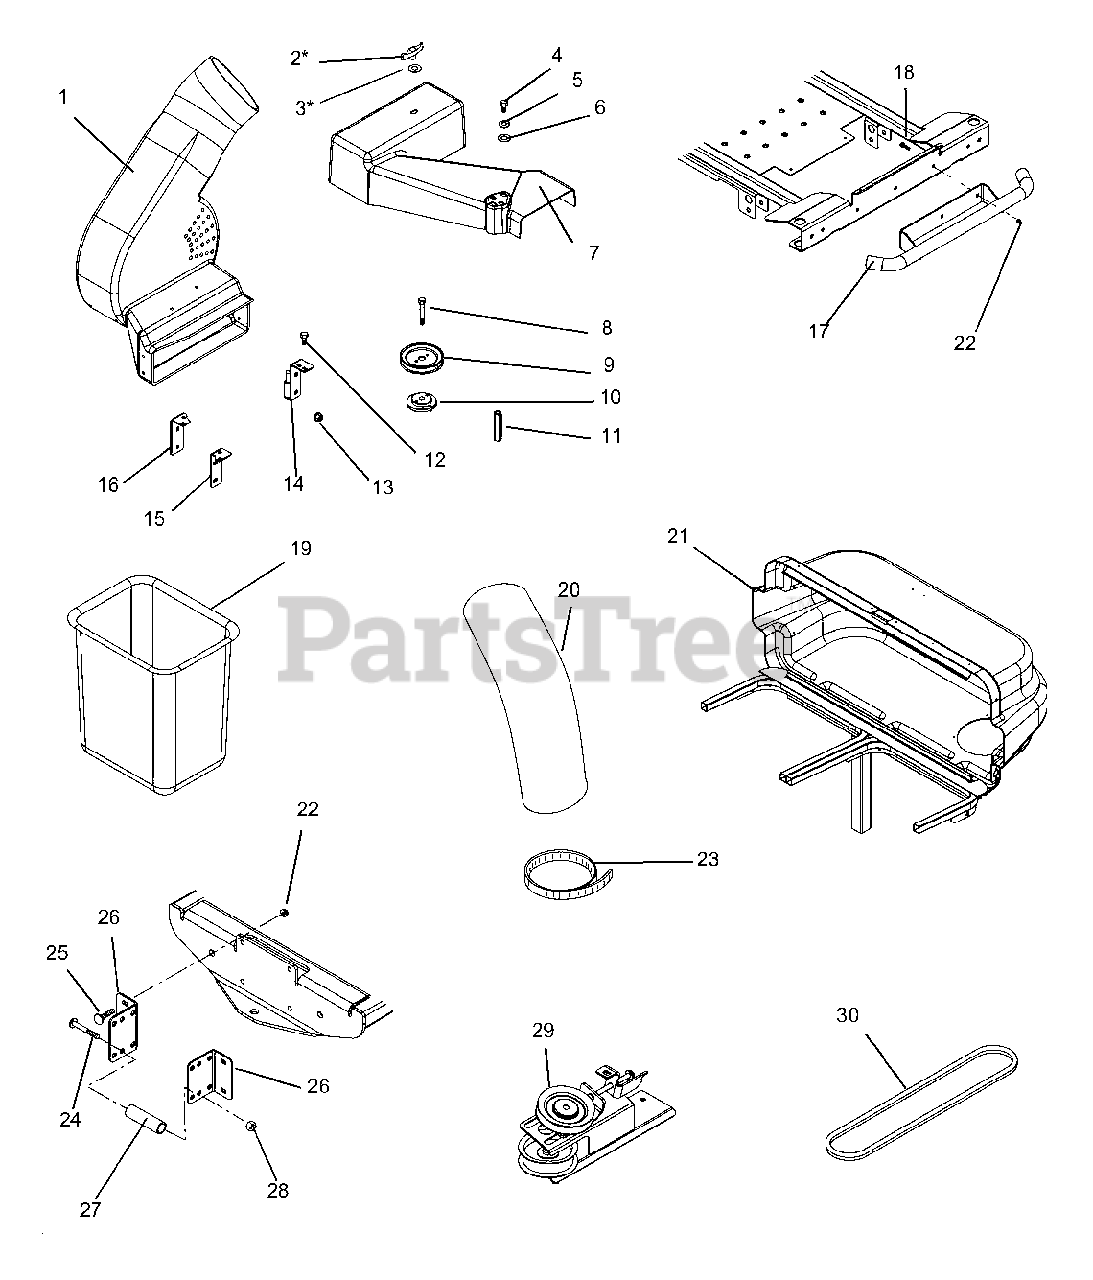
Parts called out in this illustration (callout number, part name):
1	BLOWER (SERVICE ASSEMBLY)
2	KNOB - WING .312-18 UNC
3	WSHR-FL-STL .380X1.50X.062 YWZ
4	@BLT-HEX .38-16X.75 GR5 YWZC
5	@WSHR-LK .38X.094 REG YWZC
6	@WSHR-FL-STL.438X1.00X.083 YWZ
7	BELT COVER W/DECAL
8	BLT-HEX .38-16X1.75 GR8 M-EPYZ
9	SHEAVE, 3.00 DIA.
9	SHEAVE, 4.00 DIA.
10	ASSEMBLY, SHEAVE ADAPTER
11	NUT, COUPLING .38-16 X 2.97
12	@BLT-HEX .25-20X.75 GR5 YWZC
13	@NUT-LK-TOP-FLG .25-20 YWZC
14	WELDMENT, REAR MOUNT BRACKET
15	BRACKET, FRONT
16	WELDMENT, FRONT MOUNT BRACKET
18	@BLT-HEX .38-16X1.00 GR5 YWZC
19	GRASS BAGGER BASKET
20	HOSE 7X38
21	Cover Assembly
22	@NUT-LK-NYL-FLG .38-16 YWZC
23	CLAMP, 7" TOOL-LESS HOSE
24	@BLT-HEX .50-13X3.00 GR5 YWZC
25	@BLT-RDHDSQNK .38-16X1.25 G5YZ
26	BKT,BAGGER MOUNT
27	SPACER, PIVOT .500X.750X1.805
28	@NUT-LK-TOP-FLG .50-13 YWZC
29	Idler Assembly
30	V-BELT, HA-WRAPPED
